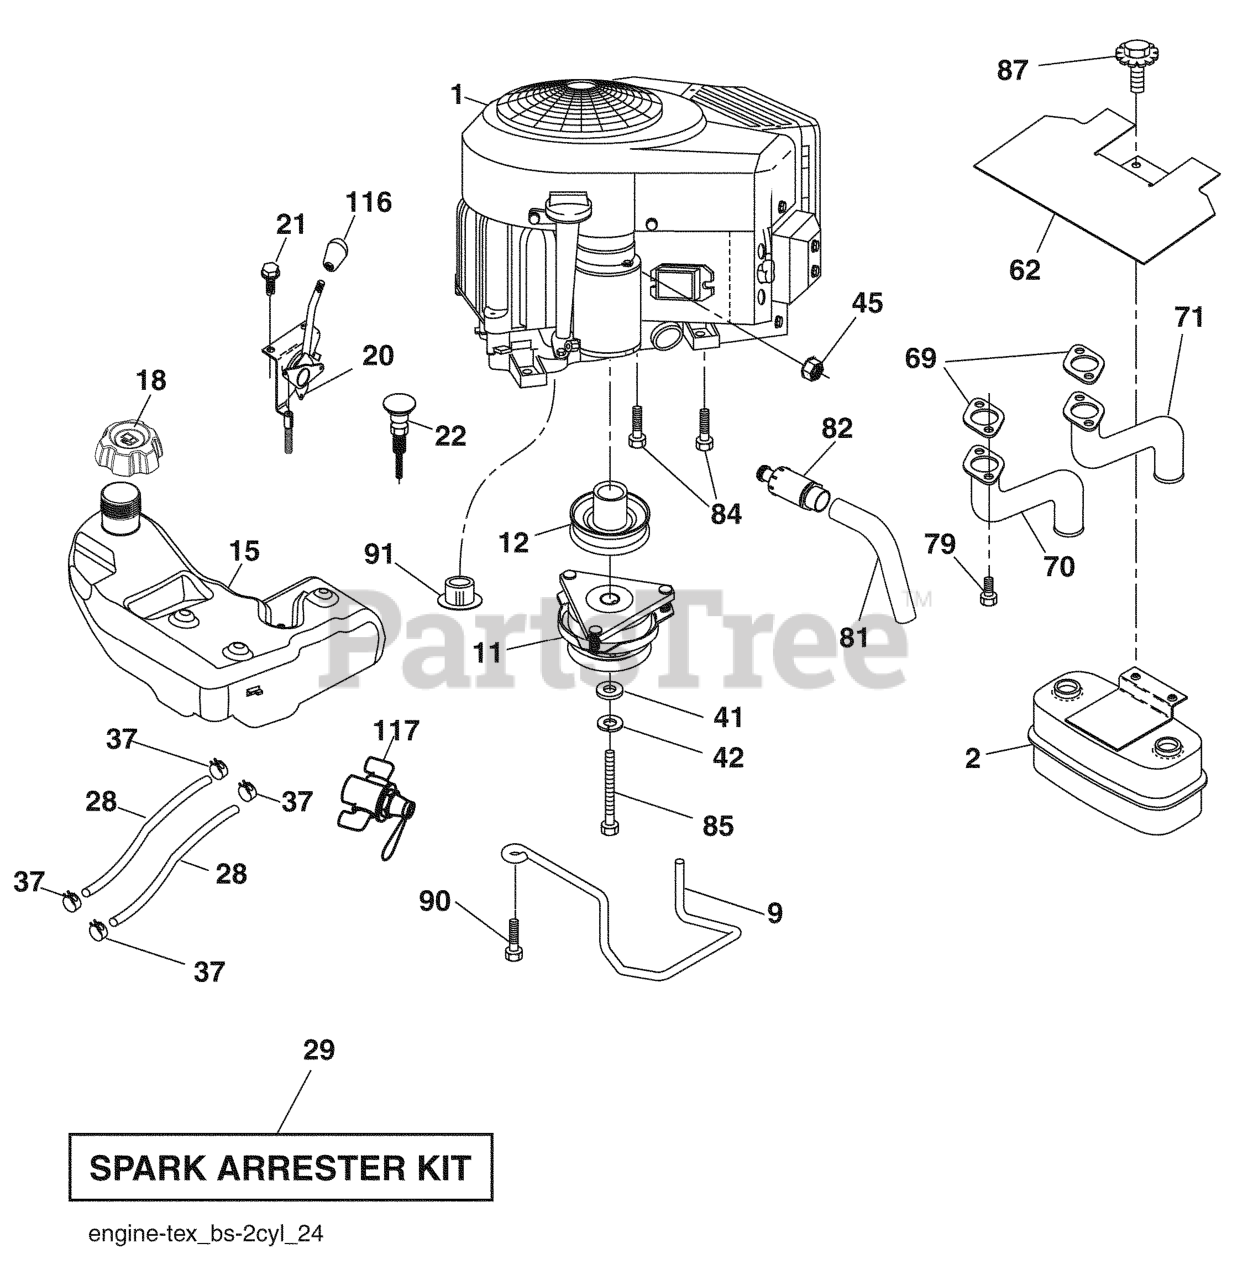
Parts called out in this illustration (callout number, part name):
2	MUFFLER.TWIN.CYL.LOW.TONE
9	KEEPER.BELT.ENGINE.4.2
11	CLUTCH.ELECTRIC.LT.48"*
12	PULLEY.ENGINE.TUFFTORQ
18	CAP.FUEL.TANK.3"GREY
20	CONTROL.THROTTLE.PRO.
21	SCREW.#10 X 0.750.BOS
22	CONTROL.CHOKE.ERGO.PUSH-IN.BLA
28	LINE.FUEL.64"REAR.EMIS
29	KIT.SPARK ARRESTOR 794945 B&S
37	HOSE CLAMP
42	LOCKWASHER
45	NUT
62	RP SHIELD HEAT MUFFLER
69	GASKET.MUFF 806237 NOW 806425
70	EXHAUST.TUBE.MUFFLR.LH.VANG
71	EXHAUST.TUBE.MUFFLR.RH.VANG
79	SCREW.TUBE.MUFFLER.VANGUARD
81	TUBE, DRAIN OIL ASM.
82	PLUG DRAIN OIL EASY
84	SCREW.3/8-16
85	BOLT HEX 7/16-20X4-1/4"
87	BOLT 5/1618UNC X 3/4 W/ SEMS
90	SCREW 3/8-16X1
91	BUSHING.1.375OD
116	RP KNOB SOFT TOUCH
117	VALVE FUEL RESERVE
